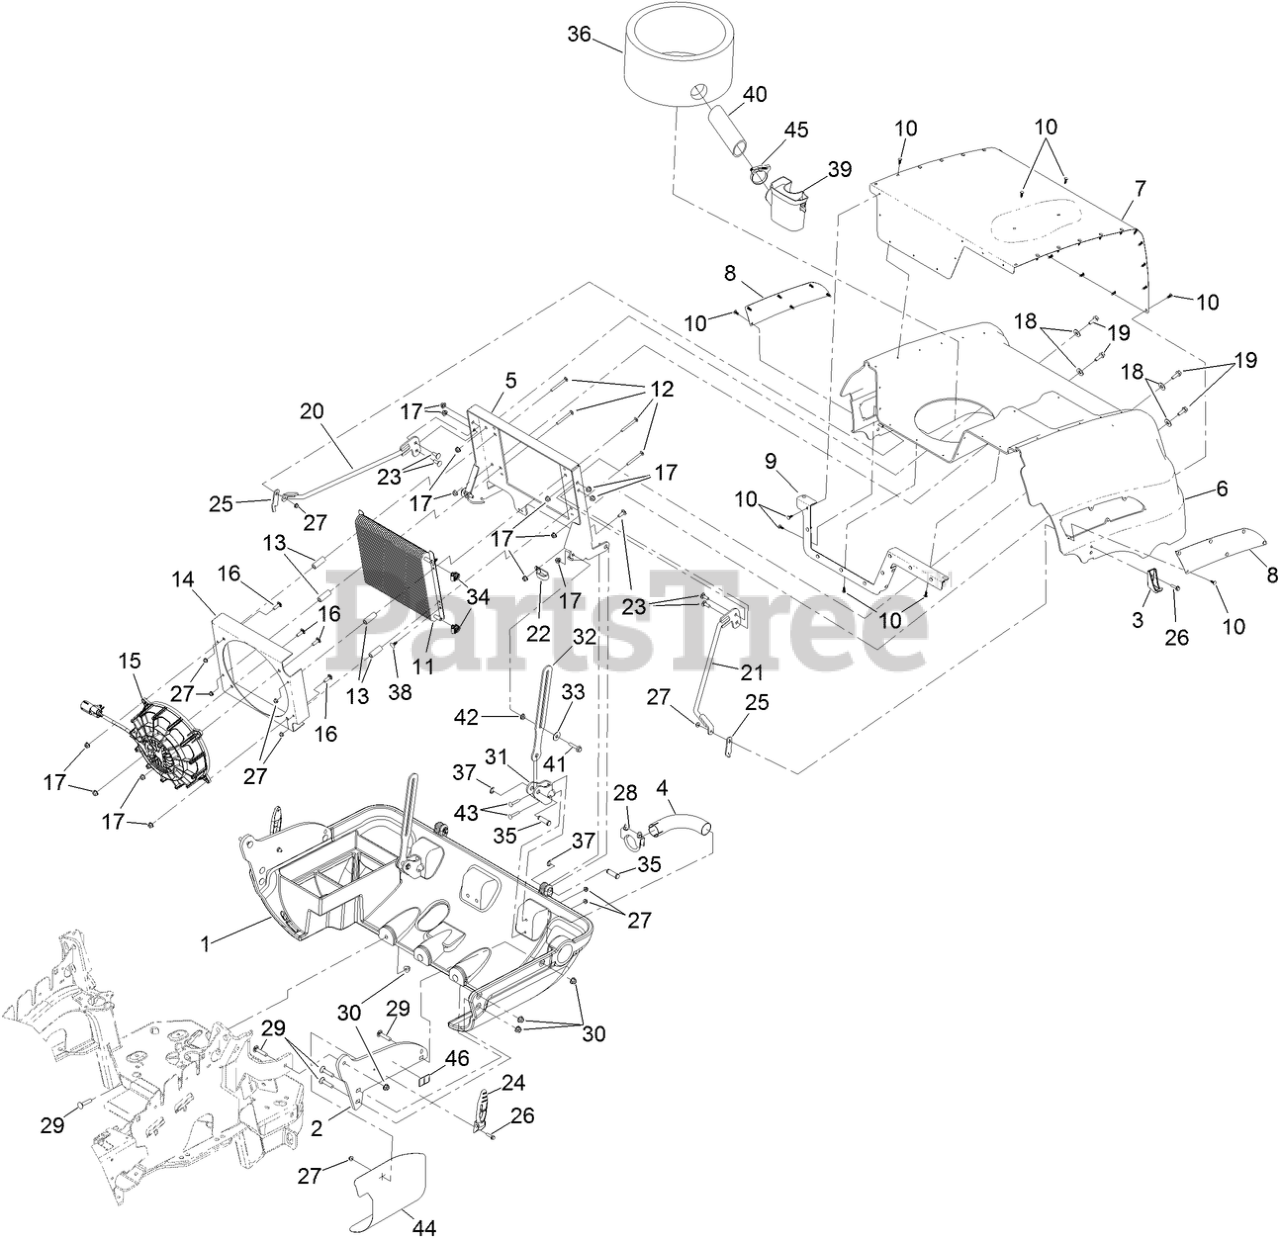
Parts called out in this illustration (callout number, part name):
1	CASTING-LOWER, REAR
2	PLATE-MOUNT
3	LATCH-CATCH
4	TUBE-EXHAUST
5	MOUNT-COOLER
7	SCREEN-INTAKE
8	SCREEN-INTAKE
9	CAP-PERFORATION, HOOD
10	PLUG-PLASTIC
11	COOLER-OIL
12	SCREW-CARR
13	SPACER
14	MOUNT-FAN
16	SCREW-CARR
17	NUT-HF, NI
18	WASHER-FLAT
19	SCREW-HHF
20	SUPPORT-HOOD, RH
21	SUPPORT-HOOD, LH
23	BOLT-CARR
24	LATCH-RUBBER
25	STOP-HOOD
26	SCREW-HHF
27	NUT-HF
28	CLAMP
29	SCREW-CARR
30	NUT-HF, NI
31	BRACKET-MOUNT, SLIDE
32	SLIDE-HOOD
33	WASHER-PLASTIC
34	CLAMP-HOSE
36	FOAM-INLET, AIR
37	RING-RETAINING, EXTERNAL
38	PLUG-PLASTIC
39	MOUNT-HOSE
40	HOSE-AIR INTAKE
41	SCREW-HHF
42	NUT-HF
43	SCREW-CARR
44	BARRIER-HEAT
46	DECAL-WARNING
